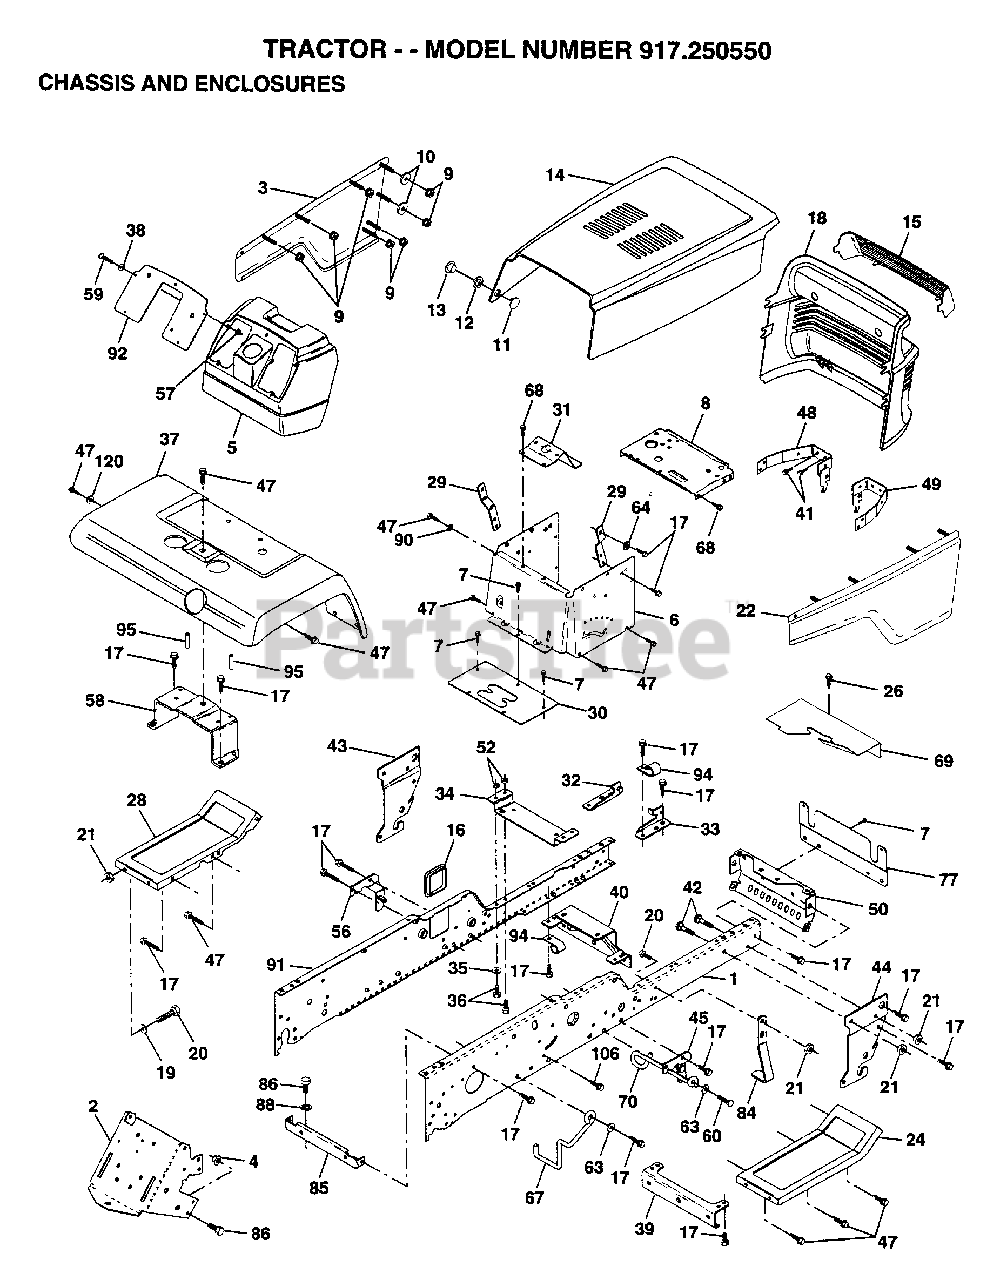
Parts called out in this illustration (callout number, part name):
2	DRAWBAR GT
3	PANEL.ASM.SIDE.LH
4	NUT.7/16
5	DASH.PLASTIC.BLK
6	DASH.1PC.LOWER
7	SCREW
8	SUPPORT.DASH.BTRY
9	PAL NUT LT
10	WASHER
11	RIVET.RATCHET.MAL
12	WASHER.NYLON
13	RIVET.RATCH.FEMAL
14	HOOD.ASM.YT/GT
16	COVER ACCESS
17	SCREW
19	WASHER
20	BOLT
22	PANEL.ASM.SIDE.RH
24	FOOTREST.RH.LT-GT
26	SCREW
28	FOOTREST.LH.LT-GT
29	BRACKET.SUPT.DASH
30	SADDLE SILKSCRN
31	BRAKET.SUPT.STEER
32	BRACKET ASM FRAME
33	BRACKET ASM FRAME
34	BRACKET.ENG.SUPT.
35	WASHER
36	BOLT
38	WASHER PM
39	BRACKET.AXLE.FRT.
41	SCREW CRT
43	BRACKET.SUS.FT.LH
44	BRACKET.SUS.FT.RH
47	SCREW LT
50	BRACKET.CHASSIS.
57	NUT HXKEP 1/4X20
58	BRKT.ASM.FENDER
59	SCREW
60	SCREW
63	WASHER
64	WASHER.SERRATED.
67	GUIDE BELT TRANS
68	SCREW LT
69	SHIELD.FRONT
70	GUIDE.BELT.MID.SP
77	SHIELD.FRONT
84	STOP.OVER.CENTER
85	BRACKET.SUPT.TRAN
86	BOLT
88	LOCKWASHER
90	LOCKWASHER
92	PLATE.DASH.SLKSCR
94	CLIP GTV
95	NUT-PUSH YT
120	WASHER HYT
